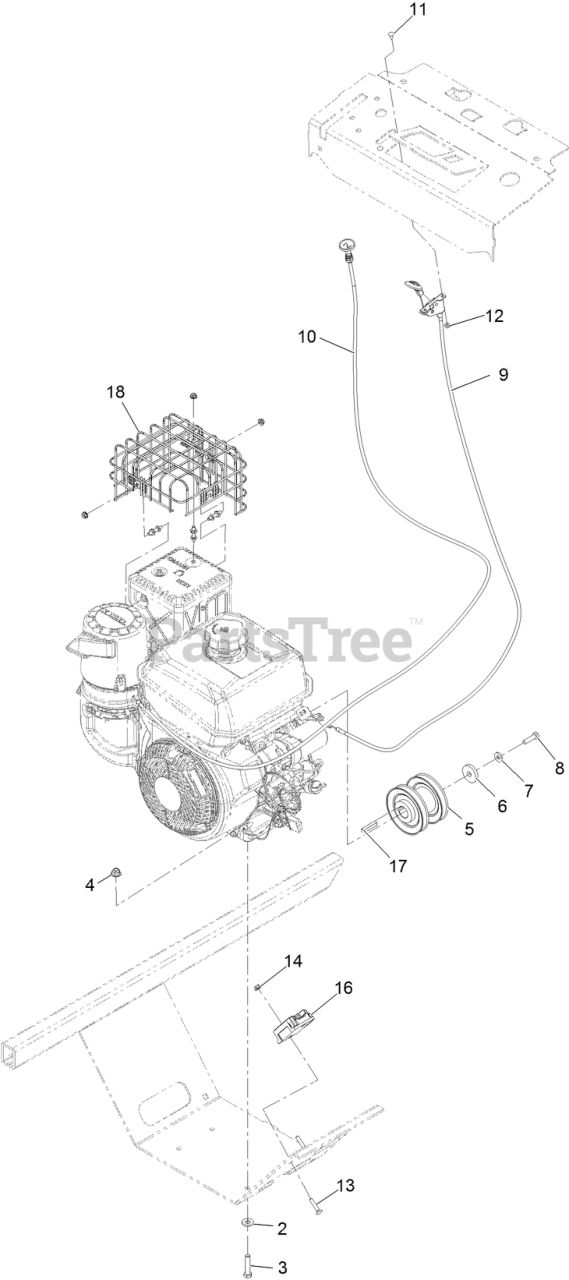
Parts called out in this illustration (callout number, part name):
2	WASHER-BELLEVILLE
3	SCREW-HH
4	NUT-HF, NI
5	PULLEY
6	WASHER-CLUTCH
7	WASHER-SPRING
8	SCREW-HH
9	CONTROL-THROTTLE
10	CABLE-CHOKE, PUSH/PULL
11	BOLT-CARR
12	NUT-LOCK, NI
13	SCREW-CARR
14	NUT-HF
16	REGULATOR
17	KEY-SQUARE, 7MM
18	KIT-MUFFLER BIRDCAGE
